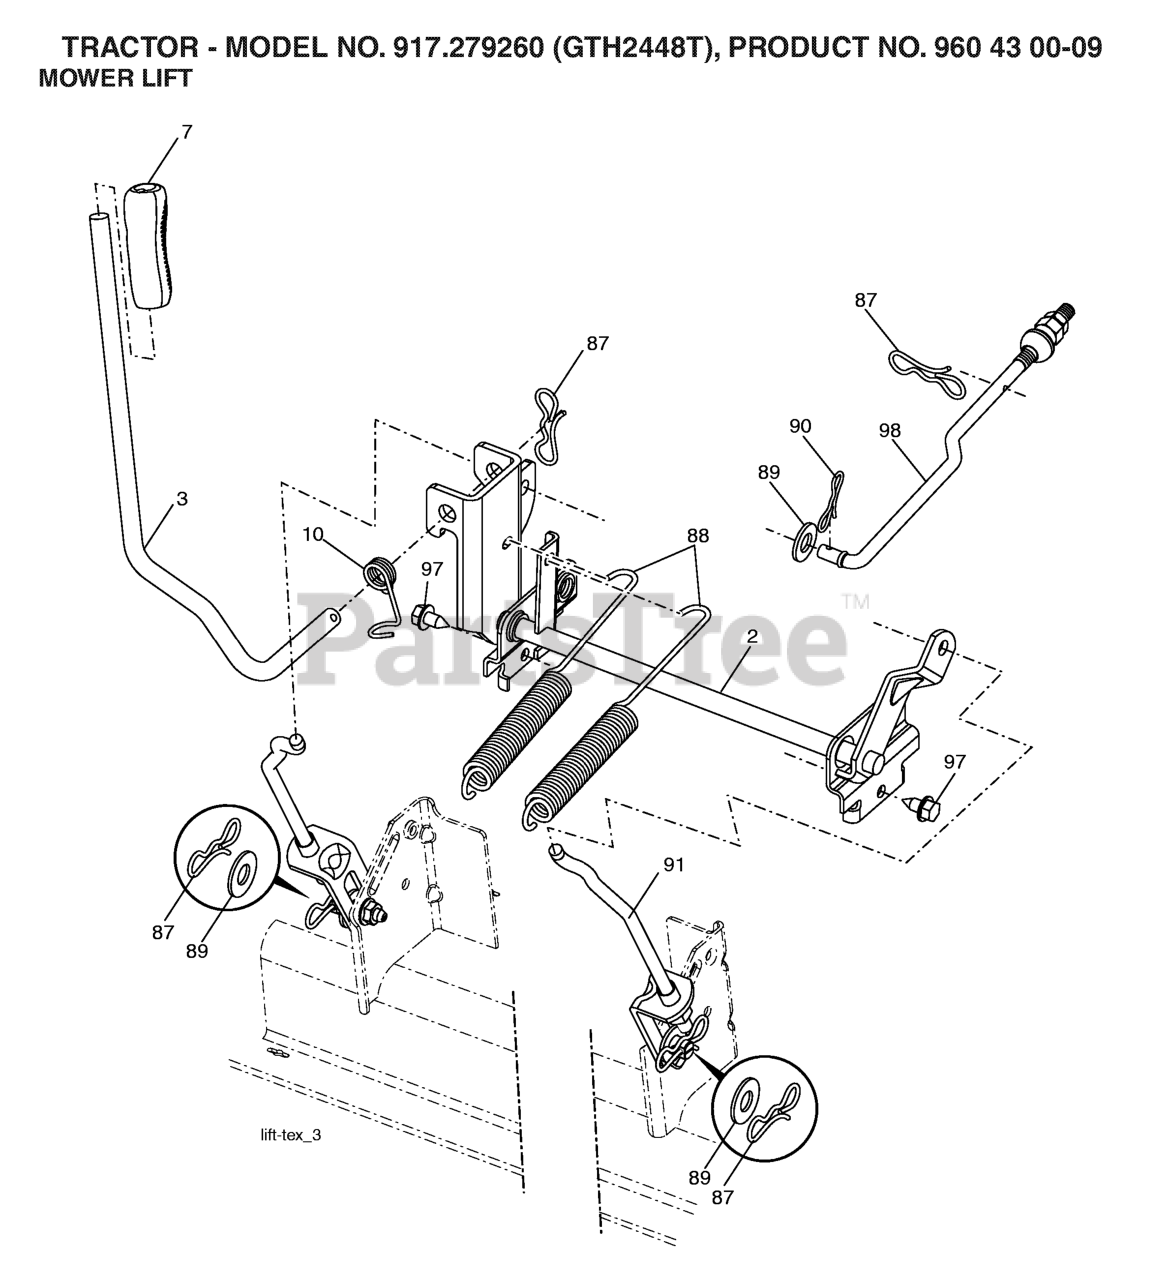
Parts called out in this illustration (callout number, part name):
2	SHAFT.ASM.LIFT.CROSS.H
3	LEVER.LIFT.HANDLE.GT
7	GRIP.LEVER.5625.ID
10	SPRING.TORSION.LIFT.HANDLE
87	PIN.COTTER.7/16.BOW TI.
88	SPRING.LIFT.ASSIST.GT2
89	WASHER.CLEAR.ZINC
90	PIN.COTTER.5/16.BOW TI
91	LINK.LIFT.ASM.REAR.GT.
92	BRACKET CONNECT LINK LIFT
95	BUSHING ALIGNMENT LINK LIFT
97	SCREW 3/8-16X3/4
98	LINK.ASM.SUSP.FRONT.MWR.10.5
99	BUSHING SPHERICAL SUSP. FRONT
100	NUT **
